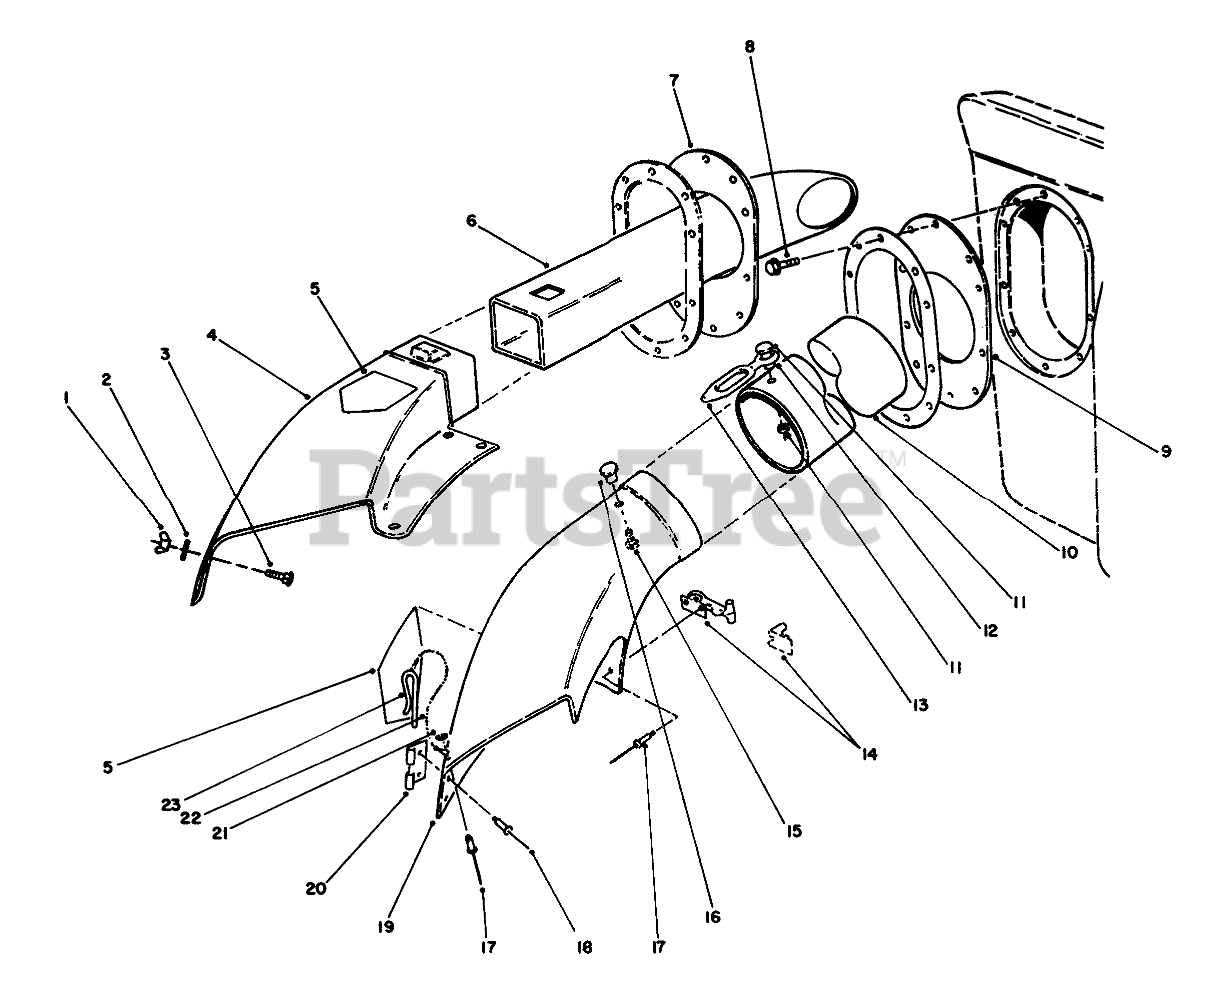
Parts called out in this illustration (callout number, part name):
1	Nut-Wing
2	Washer
3	Bolt-Carriage
4	Elbow Assembly-30" (Incl. Ref. #5)
5	DECAL-DANGER
6	CHUTE
7	Seal-30"
8	Screw (Ref.)
9	RING-RETAINER, RUBBER
10	Duct-38"
11	FASTENER-PANEL
12	SPACER-INTERLOCK
13	RETAINER-DUCT
14	Latch-38"
15	Screw
17	RIVET-POP
18	RIVET-BLIND
19	Elbow Assembly-38" (Incl. Ref. #5 & 14-23)
20	BRACKET-MOUNTING, CHUTE
21	WASHER-PLAIN
22	LANYARD
23	PIN-LOCKING, CHUTE
